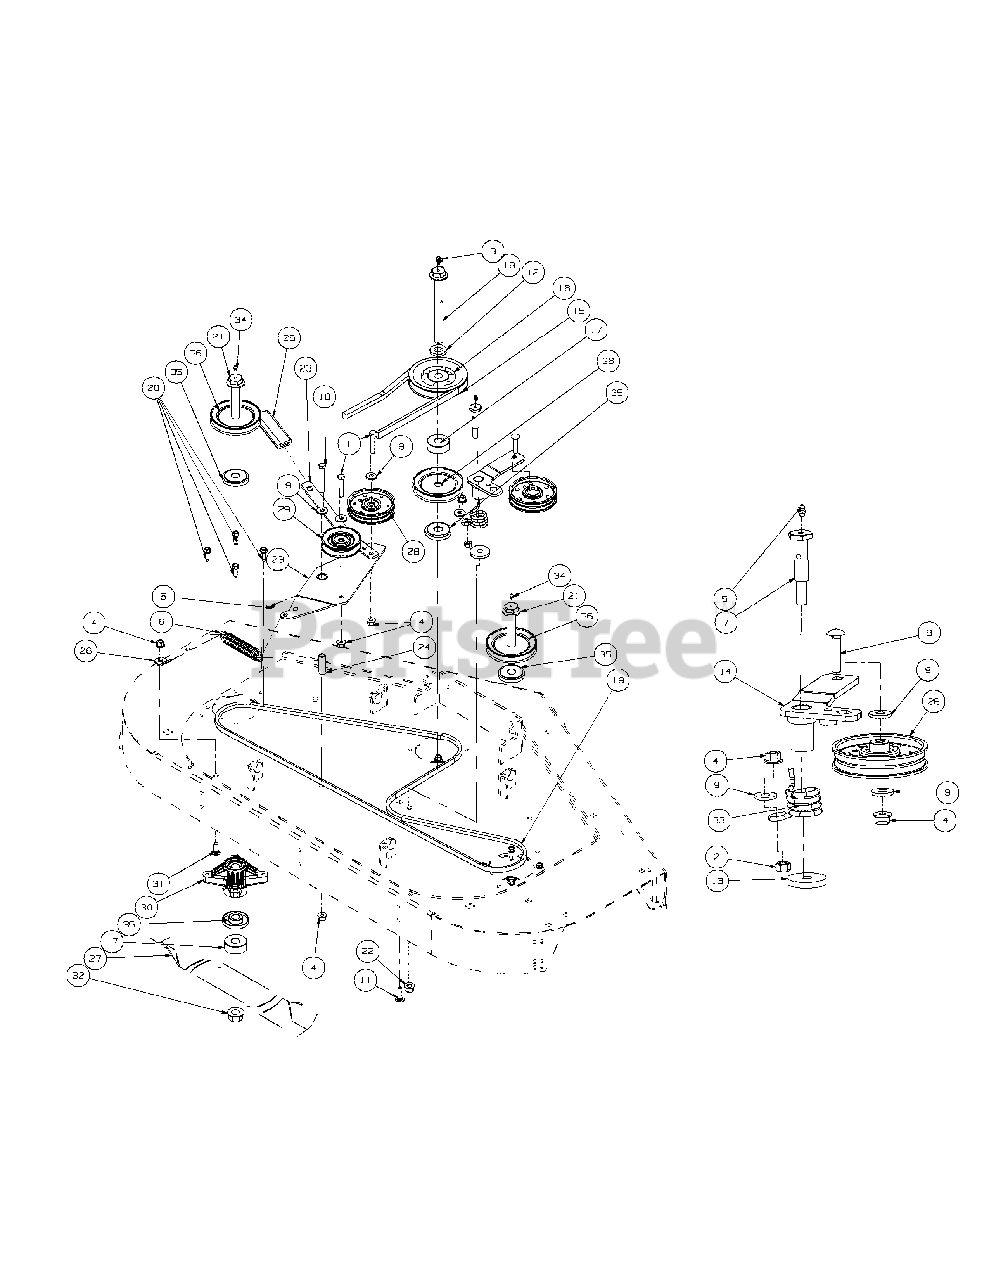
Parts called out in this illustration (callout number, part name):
1	Hex Cap Screw, 3/8-16 x 2.00
2	Hex Nut 3/8-16
3	Grease Fitting, 90 degree
4	Hex Nut, 3/8-16 Flange Lock
5	Grease Fitting, 1/4-28 x 3/16
6	Extension Spring, 1.0 OD x 5.00
7	Shoulder Screw, 7/16-14
8	Hex Carriage Screw, 3/8-16, 1.75
9	Flat Washer, .406 ID x 1.0 OD x .105
10	Hex Cap Screw 3/8-16 x 2.75
11	Carraige Screw, 3/8-16 x 1.25
12	Spacer, .812 ID x .218
13	Flat Washer, 7/16 ID x 1.75 OD
14	Idler Arm Assembly, Deck Spindle includes:
15	V-Belt, B Section x 84.2
16	V Pulley, 5.25 OD
17	Spacer .760 ID x 2.00 OD x 0.790
18	Spindle Bolt, 3/4-16 x 7.155
19	V-Belt, 1/2 x 90.9 LG
20	Self Tapping Screw 5/16-18 x 1.00
21	Spindle Bolt 3/4-16 x 5.37
22	Nut, 7/16-20, FlangeLock
23	Idler Arm Assembly, Double, includes:
24	Spacer, .39 ID x .625 OD x 1.875
25	Grip, 1.0 x 3.2 x .25
26	Tension Spring Bracket
27	Blade, 19.0, Hi-Lift, 0.756 ID
28	Flat Pulley
29	V-Pulley, 3.5 OD
30	Spindle Assembly
31	Carriage Bolt, 3/8-16 x 1.00
32	Hex Flange Nut, 3/4-16
33	Torsion Spring Idler
34	Grease Fitting
35	Spindle Spacer
